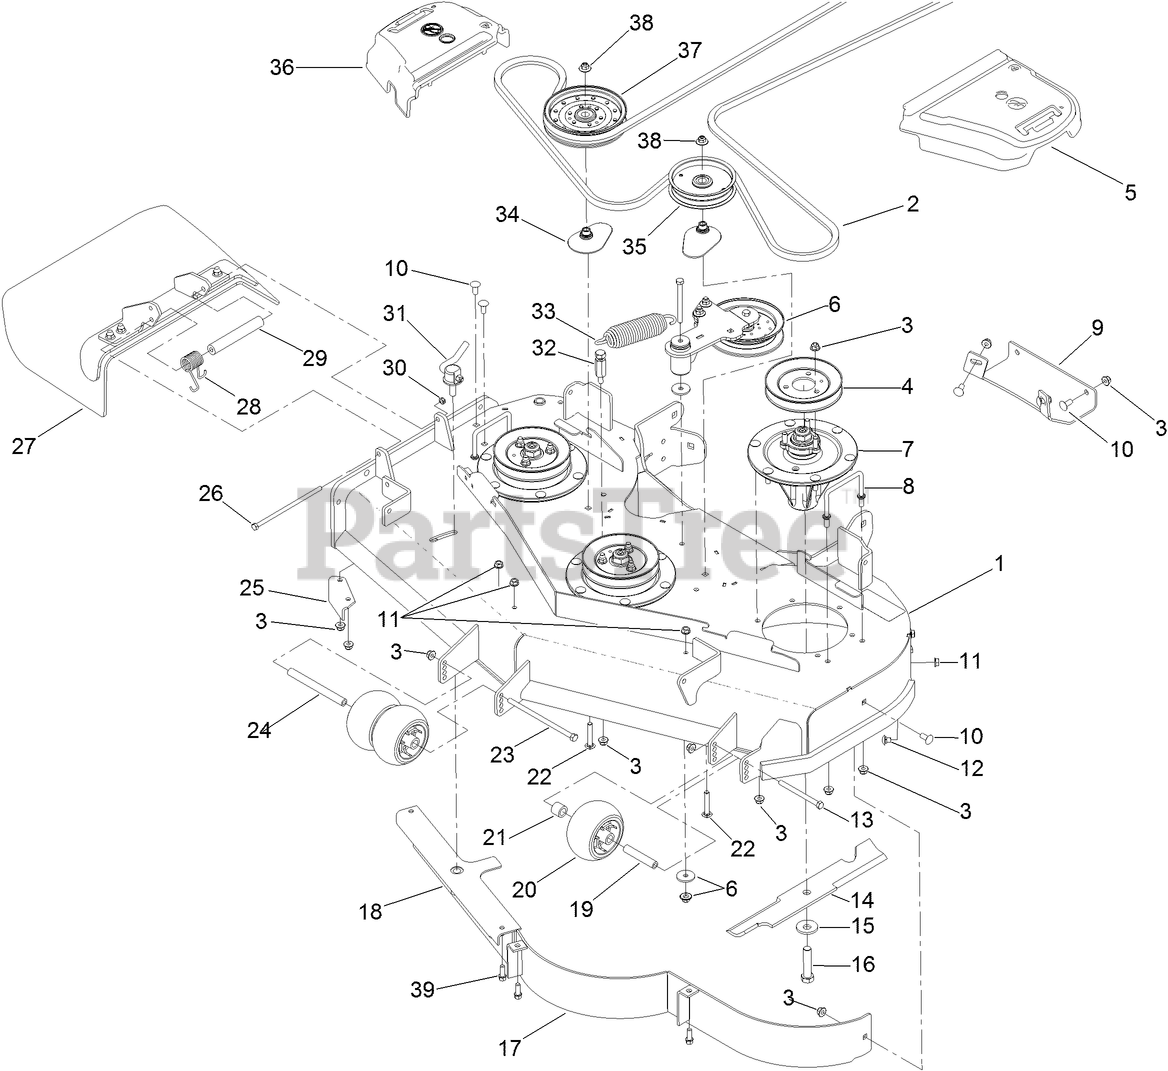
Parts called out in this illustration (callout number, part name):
1	DECK DECAL ASM
2	BELT-V
3	NUT-HF, NI
4	PULLEY
5	COVER-BELT, LH
6	IDLER ARM ASM
7	SPINDLE ASM
8	WIREFORM-COVER
9	PLATE-SKID
10	SCREW-CARR
11	NUT-HHF, WHIZ
12	SCREW-CARR
13	SCREW-HH
14	BLADE-16.5 INCH (HIGH FLOW)
15	Washer-Blade Bolt, Heavy
16	SCREW-BLADE
18	BAFFLE
19	TUBE-SPANNER
20	ROLLER-SCALP, ANTI
21	TUBE-SPACER
22	BOLT-CARR, SHORT NECK
23	SCREW-HH
24	SPACER-WHEEL
25	BAFFLE-DISCHARGE
26	SCREW-HH
27	RUBBER DEFLECTOR ASM
28	SPRING-TORSION
29	SPACER
30	NUT-LOCK, NI
31	LEVER ASM
32	ANCHOR-SPRING, TALL
33	EXTENSION-SPRING
34	SPACER-PULLEY
35	PULLEY-IDLER
36	COVER-BELT, RH
37	PULLEY-IDLER, FLAT
38	NUT-FLANGE, NI
39	SCREW-HWH
